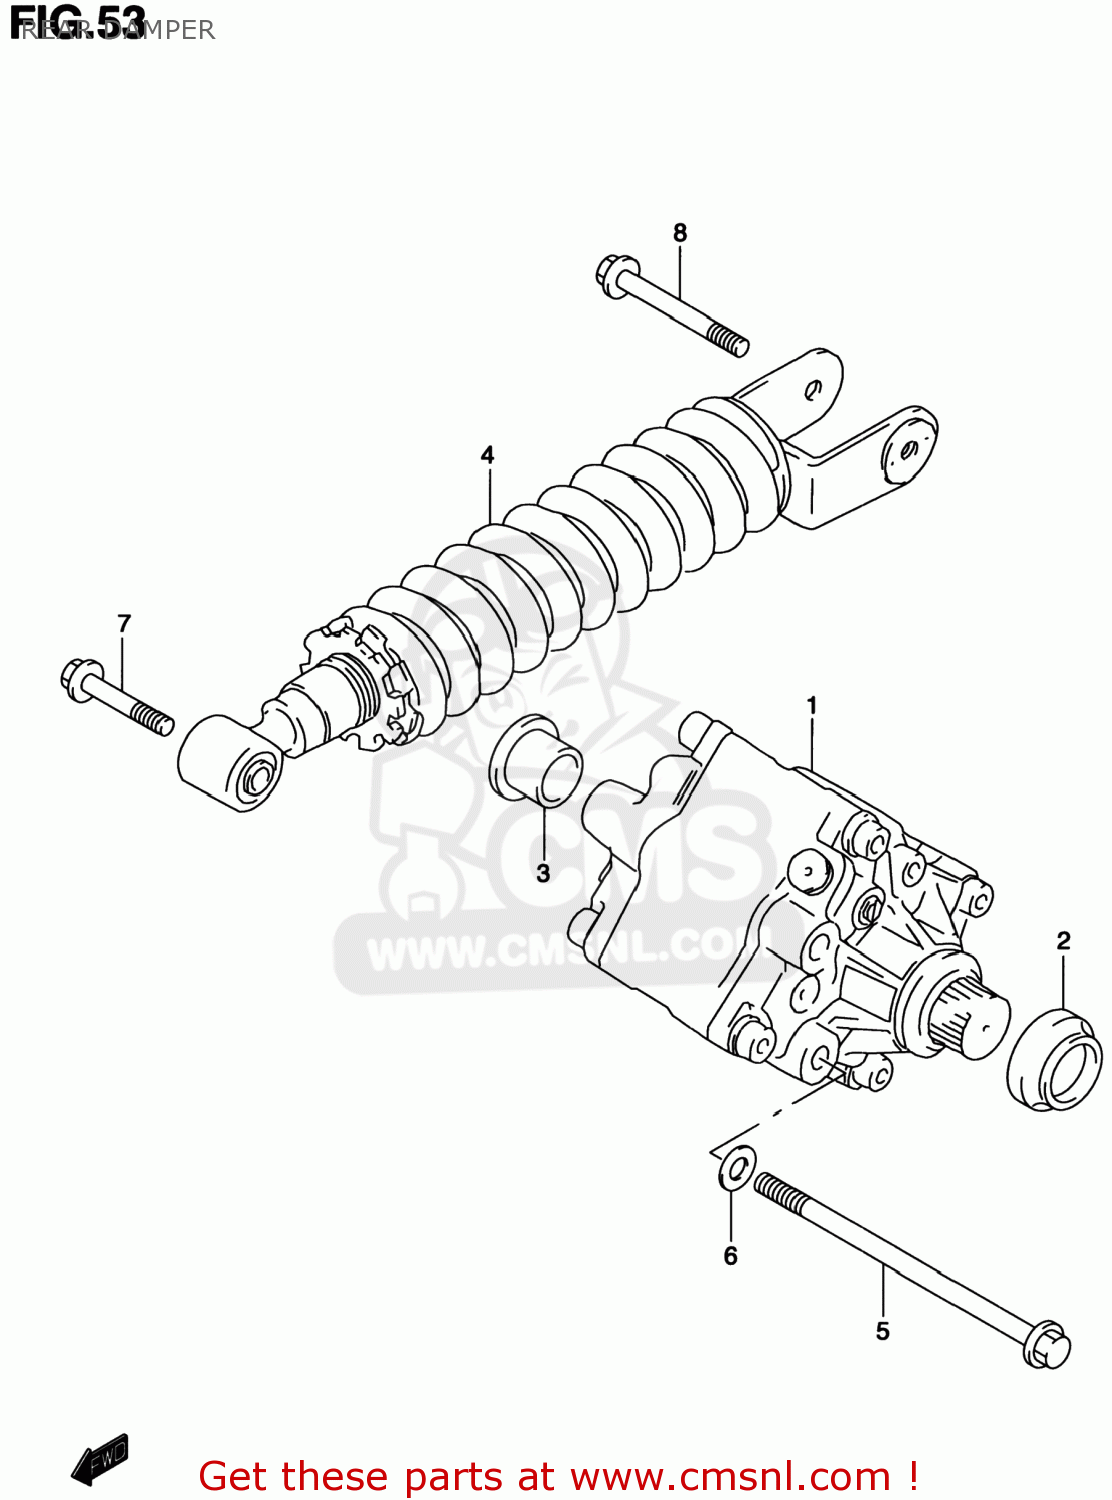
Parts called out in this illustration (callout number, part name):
1	DAMPER ASSEMBLY,REAR
2	CAP
3	CAP
4	UNIT ASSY,RR SPRING
5	BOLT(10X130)
6	WASHER
7	BOLT(10X54)
8	BOLT(10X60)
